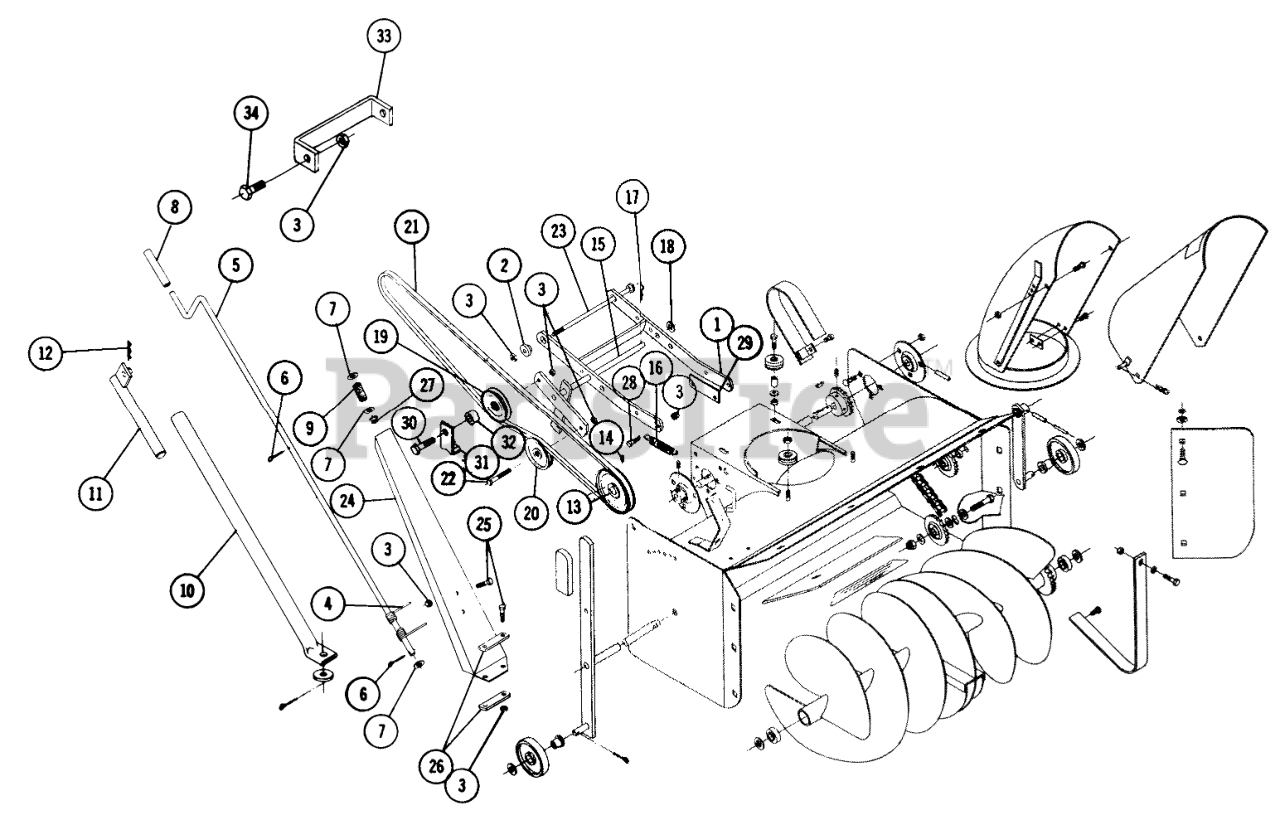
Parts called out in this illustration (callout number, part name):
1	Mounting Frame
2	Spacer
4	Cable
5	Crank
6	Cotter Pin
7	Washer
8	Tube
9	SPRING-COMPRESSION
10	Tube and Bar
11	Lift Rod
12	Hairpin
13	Pulley
14	Set Screw
15	Clip
16	SPRING R
17	Hairpin
18	Washer
19	PULLEY-IDLER
20	Idler Pulley
21	V-BELT
22	Bolt, 3/8-16 x 1/2
23	Ass-y. Rod & Spacer
24	Crank Support
25	Bolt 3/8-16 x 3/4
26	Bar-Reinforcing
27	NYLINER BUSHING
28	Bolt 3/8-16 x 1
29	Shim
30	Bolt Hex 3/8-16
31	Spacer
32	Spacer
33	Bracket-Steering Stop
34	Bolt 3/8-16 x 1
